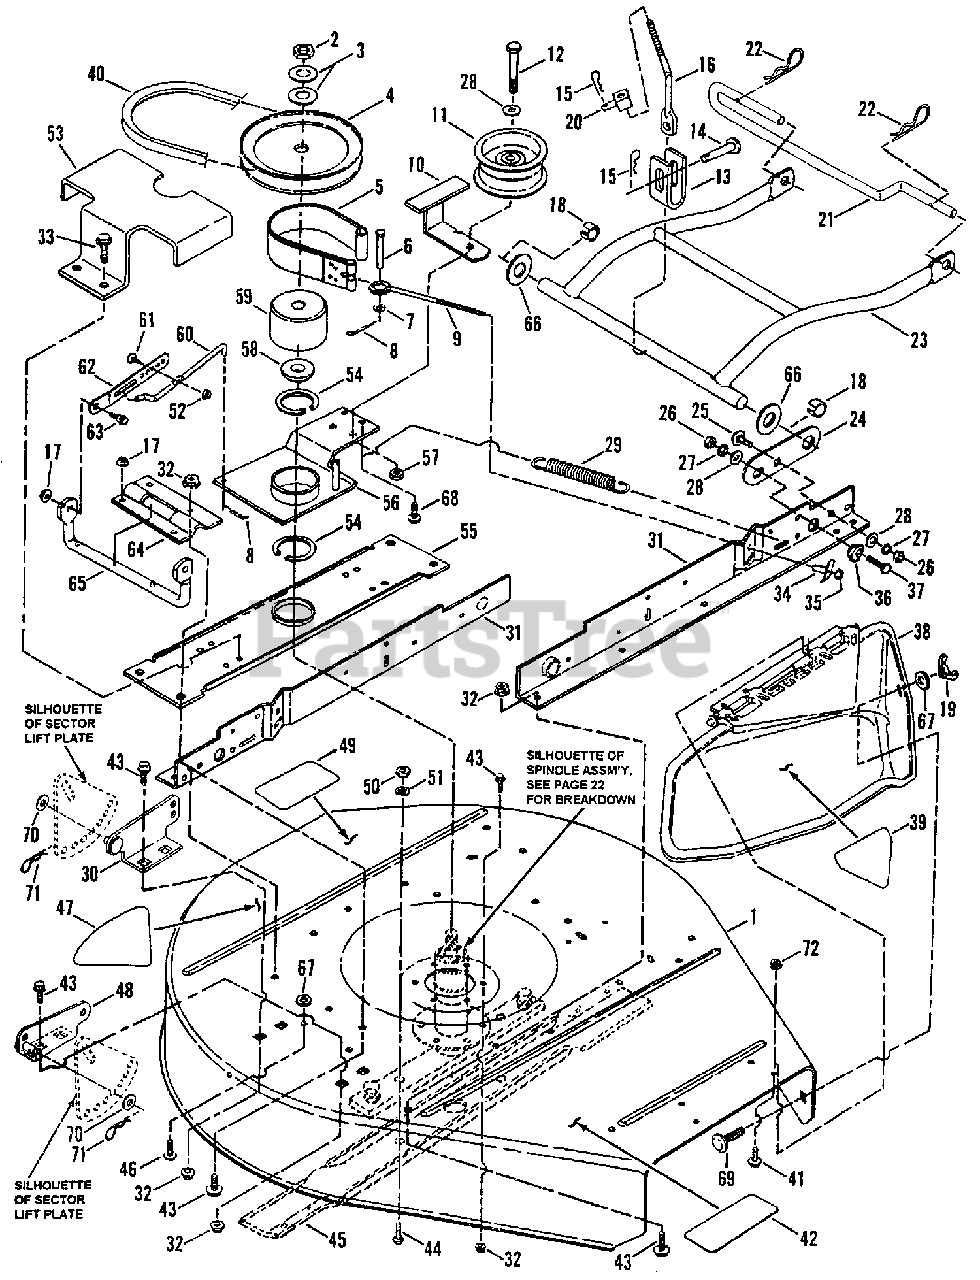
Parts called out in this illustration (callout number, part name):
1	DECK, 30" Cutting
2	NUT, 3/4-16 Hex Jam
3	WASHER, Flat
4	PULLEY, Spindle, 6 1/2" O.D.
5	ASSEMBLY, Brake Band
6	PIN, 1/4 x 1-1/4" Clevis
7	WASHER, Flat
8	COTTER-PIN, 3/32 x 3/4"
9	BOLT, 1/4-20 Eye
10	GUIDE, Belt
11	PULLEY, Idler 4.0" O.D. (Flat 3.25" Running Surface)
12	SCREW, 3/8-16 x 1 3/4" Hx. Hd. Cap
13	BRACKET, Front Lift Hanger
14	PIN, 3/8 x 1 1/2" Clevis
15	PIN, Hair, 3/32 x 1 19/32"
16	ROD, Front Lift
17	NUT, 5/16-18 Hex Flange Lock
18	RING, Front Lift Arm
19	NUT, 5/16-18 Wing
20	SWIVEL, Brake
21	PIN, Front Deck Hanger
22	PIN, .148 x 2.62" Hair
23	LIFT, Front Arm
24	LINK, Adjustment
25	BOLT, 3/8-16 x 3/4" Carriage
26	NUT, 3/8-16 Hex
27	WASHER, 3/8 Split Lock
28	WASHER, Flat, 3/8 SAE
29	SPRING, Clutch & Brake
30	BRACKET, Rear Deck Lift, Left Side
31	RAIL, 30" Cutting Deck
32	NUT, 3/8-16 Hex Flange Lock
33	SCREW, 5/16-18 x 5/8" S.T.
34	T-NUT, 1/4-20 Thread
35	NUT, 1/4-20 Hex
36	ECCENTRIC, Leveling
37	SCREW, 3/8-16 x 1" Hex Hd Cap
38	ASSEMBLY, Deflector
39	DECAL - DANGER (Cut Finger)
40	BELT, Drive, 30" Cutting Deck
41	BOLT, 5/16-18 x 1/2" Hex Flange Lock
42	DECAL - CAUTION
43	BOLT, 3/8-16 x 3/4" Hex Flange Lock
44	SCREW, 1/2-20 x 1" Hx. Hd. Cap
45	BLADE, 30" Cutting Deck
46	BOLT, 5/16-18 x 3/4" Hx. Flg. Lk.
47	DECAL, 30"
48	BRACKET, Rear Deck Lift, Right Side
49	DECAL - CAUTION, Rotating Blades
50	NUT, 1/2-20 Hex Jam
51	WASHER, 1/2 Internal Tooth Lock
52	NUT, 1/4-20 Hex Flange Lock
53	GUIDE, Belt
54	RING, 2" External Retaining
55	BRACE, Spindle
56	ARM, Idler
57	NUT, 3/8-16 Hex Center Lock
58	WASHER, Spindle
59	DRUM, Brake
60	ROD, Link, Clutch/Brake
61	BOLT, 1/4-20 x 1/2" Hex Fig. Lock
62	BRACKET, Link, Clutch/Brake
63	SCREW, 5/16-18 x 3/4" Shoulder
64	BRACKET, Pivot Arm
65	ARM, Pivot
66	WASHER, Flat
67	WASHER, 5/16 Flat
68	SCREW, 5/16-18 x 3/4" Self-Tapping
69	BOLT, 5/16-18 x 3/4" Short Neck Carriage
70	WASHER, 3/8" Flat
71	PIN, .093 x 1.50" Hair
72	NUT, 5/16-18 Hex Flange Lock
